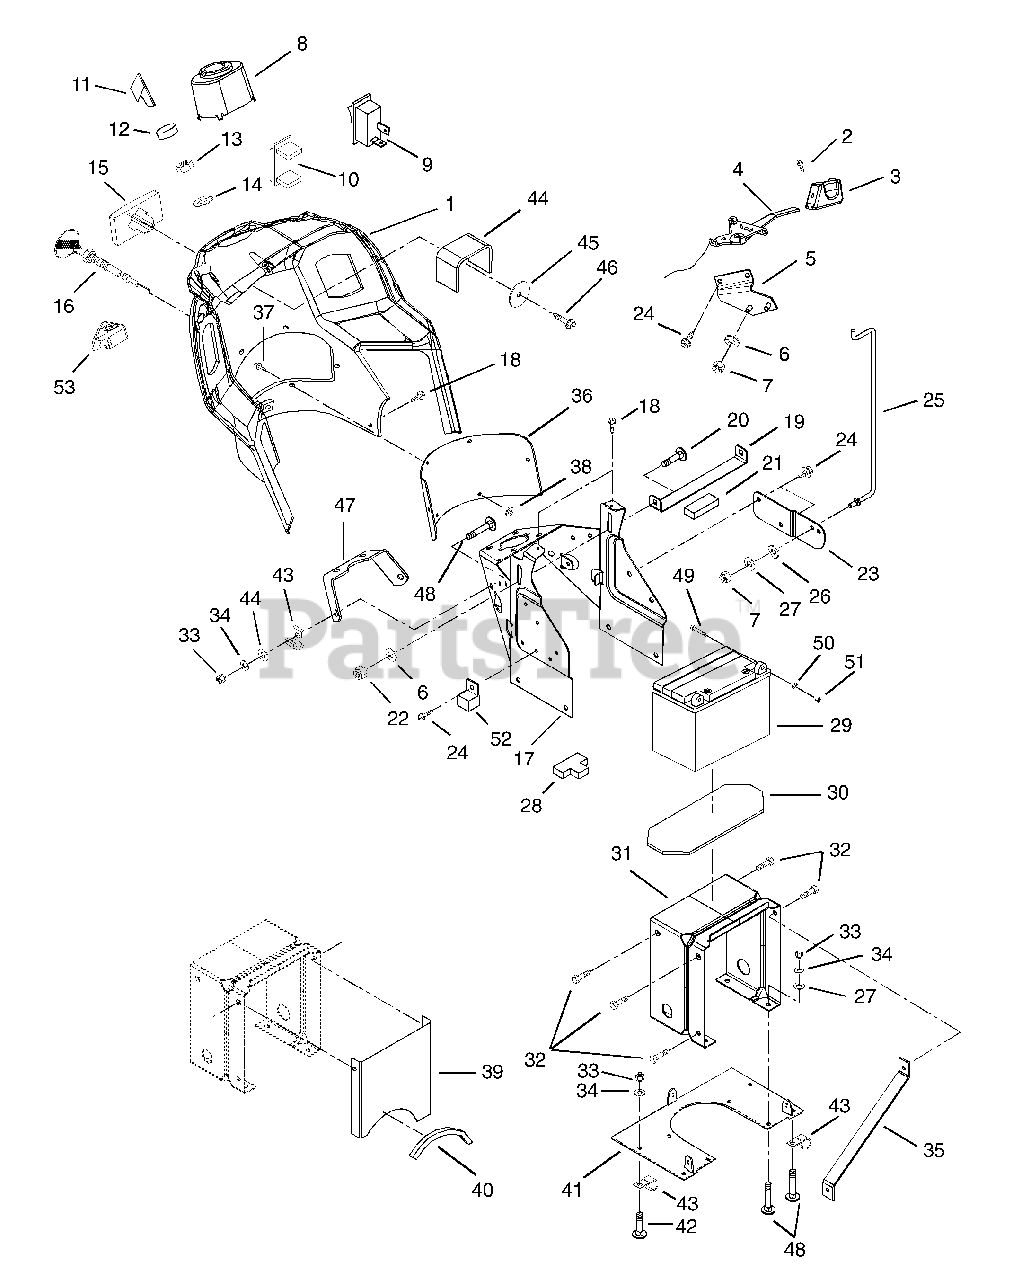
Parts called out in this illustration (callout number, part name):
2	SCR-SET 10-24X.38 UNC-3A
3	KNOB, THROTTLE
4	THROTTLE CONTROL-B&S
5	BRACE-THROTTLE CONTROL
6	WSHR-FL-STL .323X.625X.062 YWZ
7	@NUT-LK-CTR .25-20 YWZC
8	STEERING CONE
9	SWITCH - LIGHT
10	COVER - SWITCH
11	KEY -W/CAP
12	CAP - IGNITION SWITCH
13	NUT- PANEL .562-24 GRECO
14	WSHR-LK-INT .625X.045 YWZC
15	KNOB - FILLER
16	CHOKE CABLE
17	SUPPORT - DASH - TOP
18	SCR-TAP 10-24X.484 HWH TR
19	HOLDDOWN - BATTERY
20	@BLT-RDHDSQNK .31-18X.75 G5YZ
21	PAD, FOAM
22	@NUT-LK-NYL .312-18 YWZC
23	MOUNT - PROP ROD
24	@SCR-TAP .25-20X.37 HWH YWZ TR
25	ROD - HOOD PROP
26	WAVE WASHER .390X.655X.110
27	@WSHR-FL-STL.312X.734X.065 YWZ
28	INSULATOR
29	BATTERY
30	RUBBER PAD
31	SUPPORT DASH BASE
32	SCR-TAP .312-18X.50 HWH TR BL
33	@NUT-HEX .31-18 YWZC
34	WSHR-LK .312X.097 HVY YWZC
36	SCREEN - DASH
37	RETAINER, RADIATOR SHROUD
38	WSHR-FL-STL .265X.50X.087YWZC
39	SHIELD, AIR
40	TAPE-ADHESIVE BACKED FOAM
41	SUPPORT, DASH BASE (G.S. ONLY)
42	@BLT-RDHDSQNK .31-18X.75 G5YZ
43	J-CLAMP
44	SPACER-CHANNEL
45	WSHR-FL-STL .281X1.250X.048 BL
46	SCR-TAP .25-20X.75 HWH TR YWZ
48	@BLT-HEX .31-18X.75 GR5 YWZC
49	@BLT-HEX .25-20X.75 GR5 YWZC
50	WSHR-LK .250X.077 HVY YWZC
51	@NUT-HEX .25-20 YWZC
52	RELAY
53	PTO KNOB/ SWITCH ASSY
